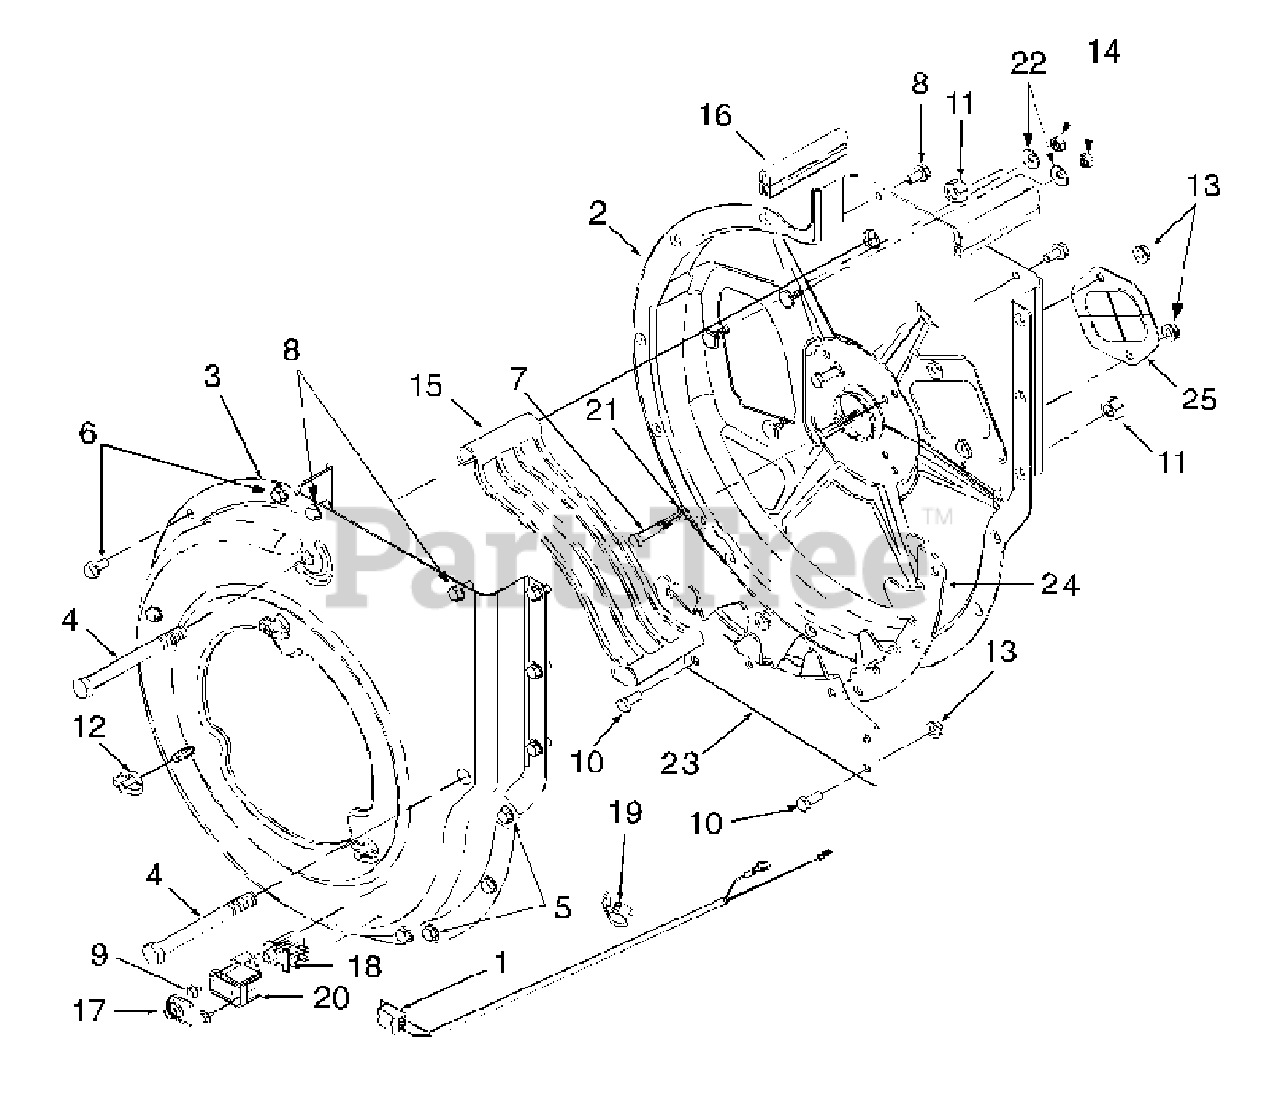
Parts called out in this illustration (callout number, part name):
1	Harness, Wire
2	Housing Ass'y, Inner Flail
3	Housing Ass'y, Outer Flail
4	Screw, Hex Cap, 1/2-13 x 5.0
5	Screw, Hex Wash Hd Tapp 5/16-18 x .62
6	Screw, Hex Wash Hd Tapp 5/16-18 x .50
7	Screw, Hex Cap, 5/16-24 x 2 GR5
8	Screw, Hex Wash Hd Tapp 5/16-18 x .75
9	Screw, Hex Wash Hd Tapp #10-16 x .38
10	Screw, Hex Cap, 5/16-18 x .75 GR5
11	Nut, Hex Center Lock, 1/2-13
12	Knob, 5/16-18
13	Nut, Hex Flange Lock, 5/16-18
14	Nut, Hex, 5/16-18
15	Screen, Discharge
16	Rubber Seal
17	Cover, Switch
18	Switch, Snap Mount
19	Clamp
20	Cover, Safety Switch Mtg.
21	Washer, Lock, 5/16
22	Washer, Bell, .345 x .88 x .06
23	Blade, Lower Shredder
24	Blade, Upper Shredder
